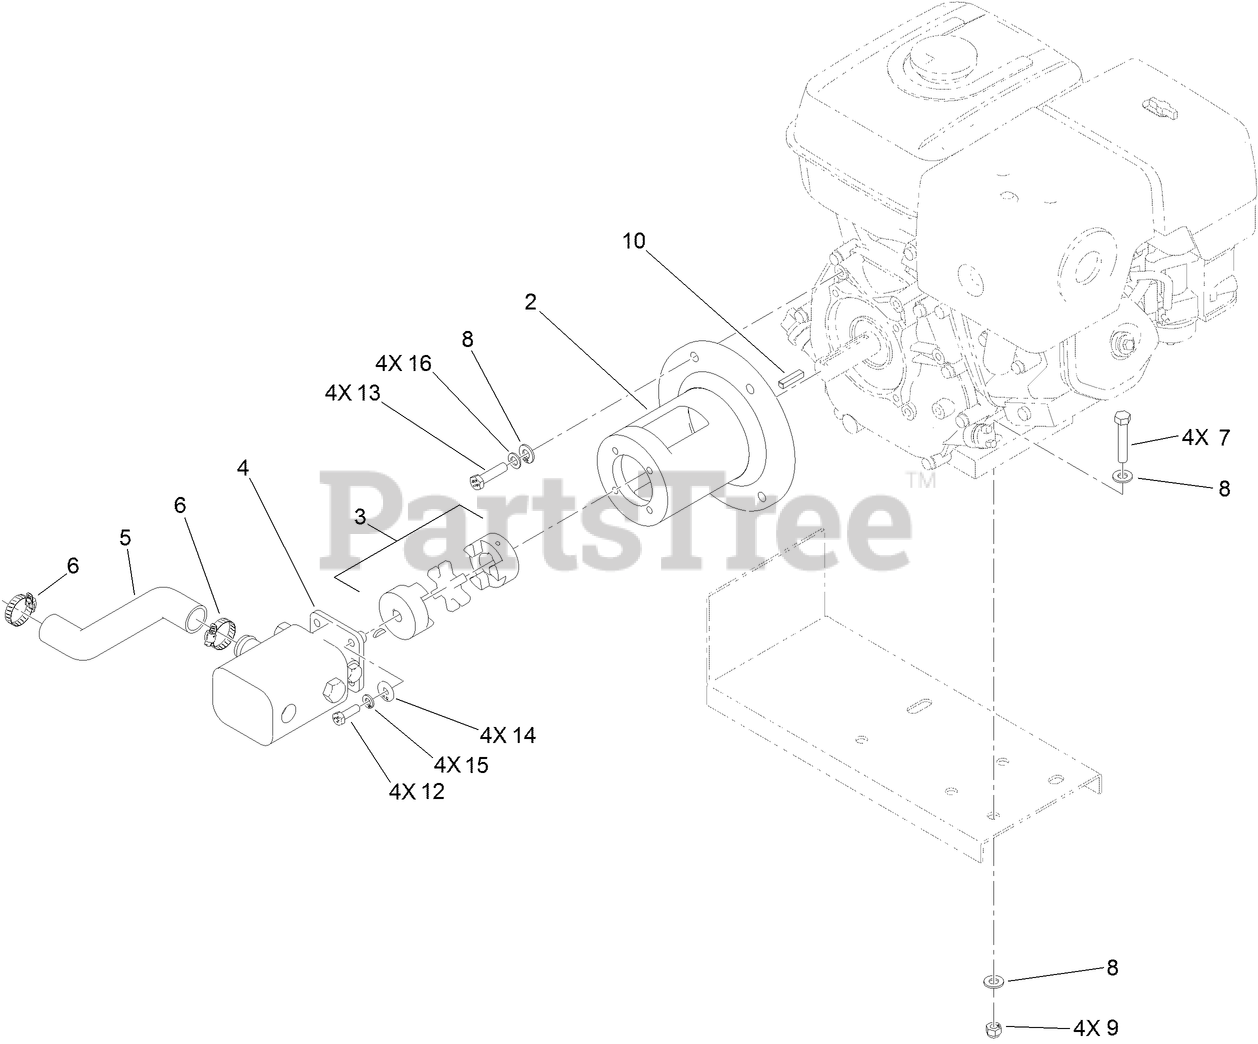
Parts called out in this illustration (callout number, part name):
2	HOUSING-MOUNT, PUMP
3	FLEX COUPLER ASM
4	PUMP-HYD
5	HOSE-SUCTION
7	SCREW-HH
8	WASHER-FLAT
9	NUT-LOCK, NI
10	KEY-SQUARE
12	SCREW-HH
13	SCREW-HH
14	WASHER-FLAT
15	WASHER-LOCK
16	WASHER-LOCK
